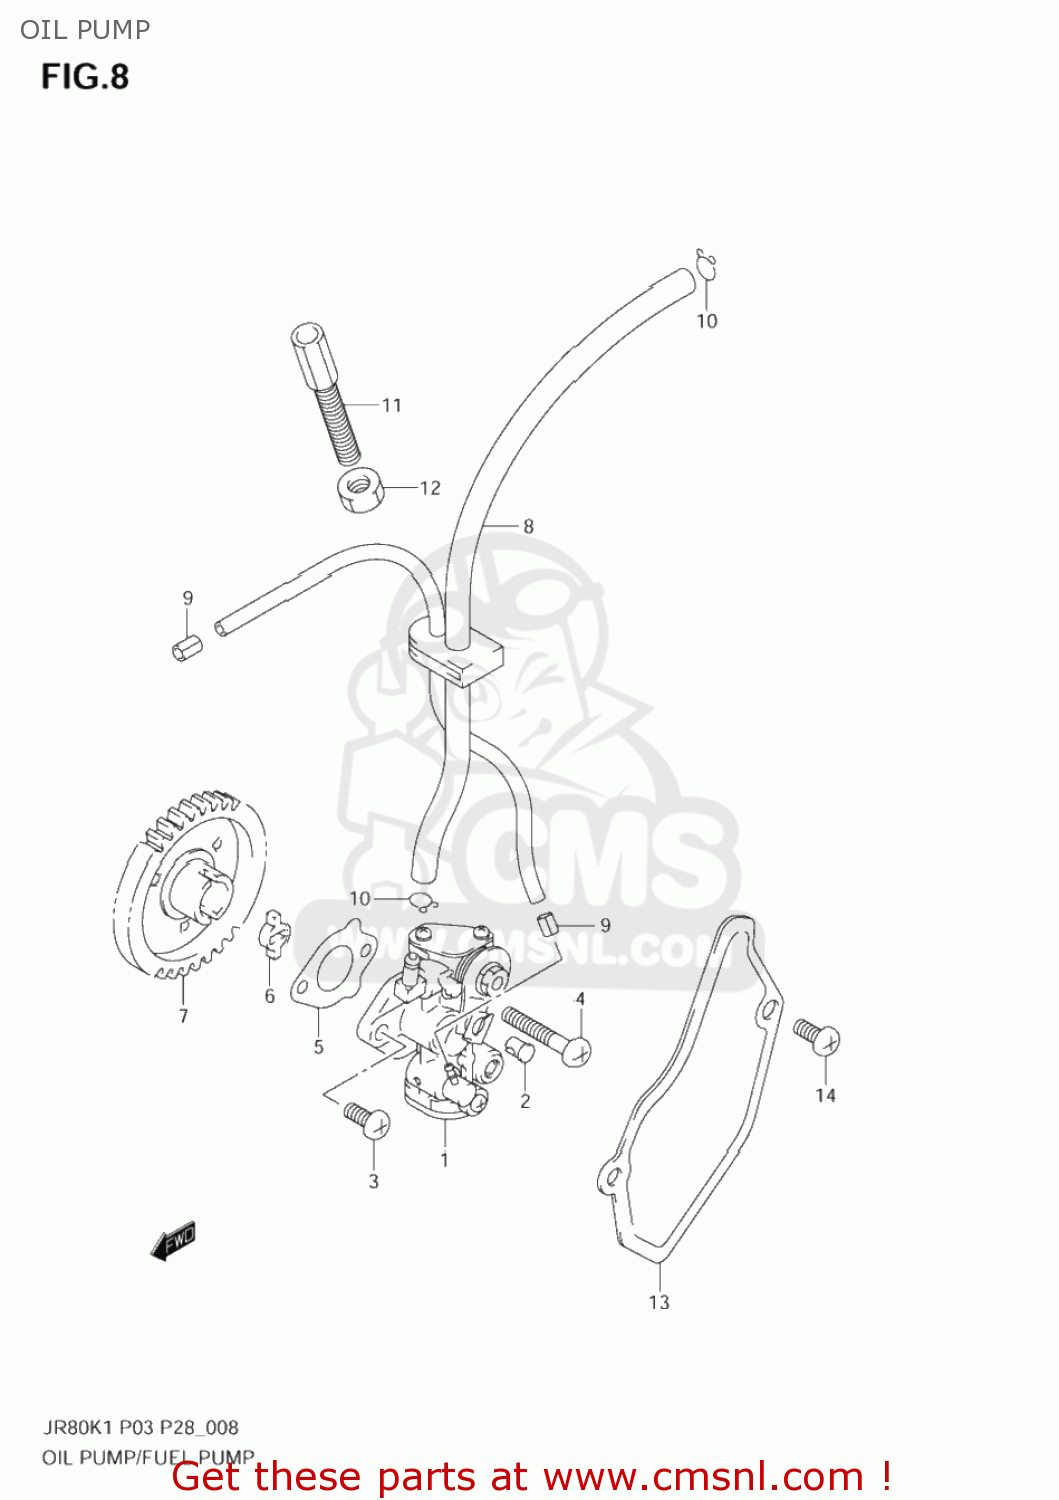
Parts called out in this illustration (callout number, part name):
1	PUMP ASSY,OIL
2	TERMINAL,CABLE
3	SCREW
4	SCREW
5	GASKET,OIL PUMP (NAS)
6	PIECE,OIL PUMP DRIVE
7	GEAR,OIL PUMP DRIVE
8	HOSE,OIL NO.2
9	CLIP
10	CLIP
11	BOLT
12	NUT
13	CAP,OIL PUMP INSPECTION
14	SCREW
